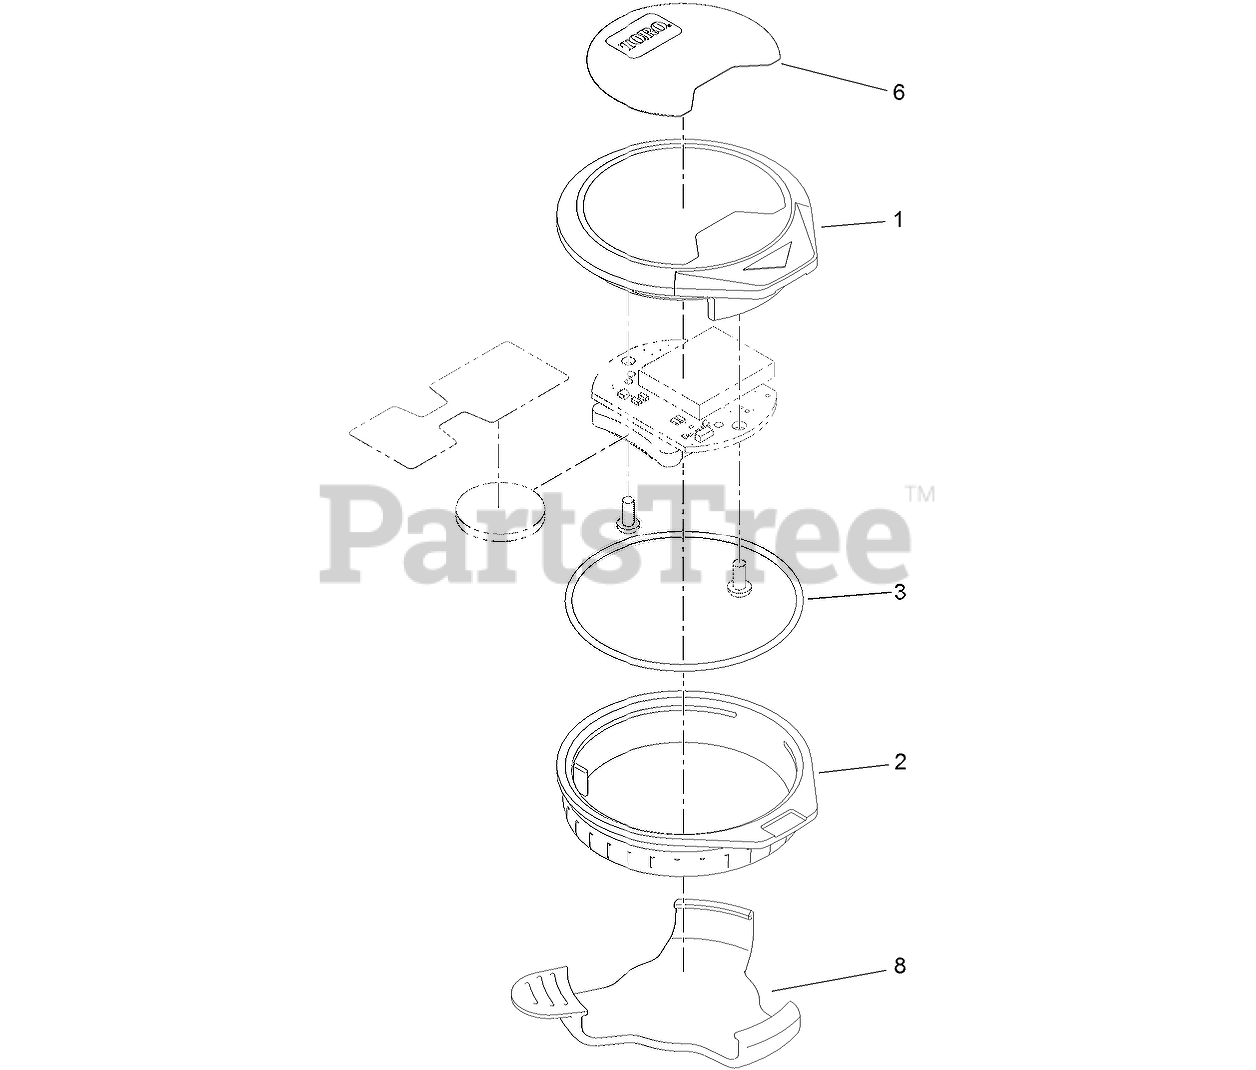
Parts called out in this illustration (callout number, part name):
1	HOUSING-TOP
2	HOUSING-BOTTOM
3	O-RING
8	CLIP ASM
